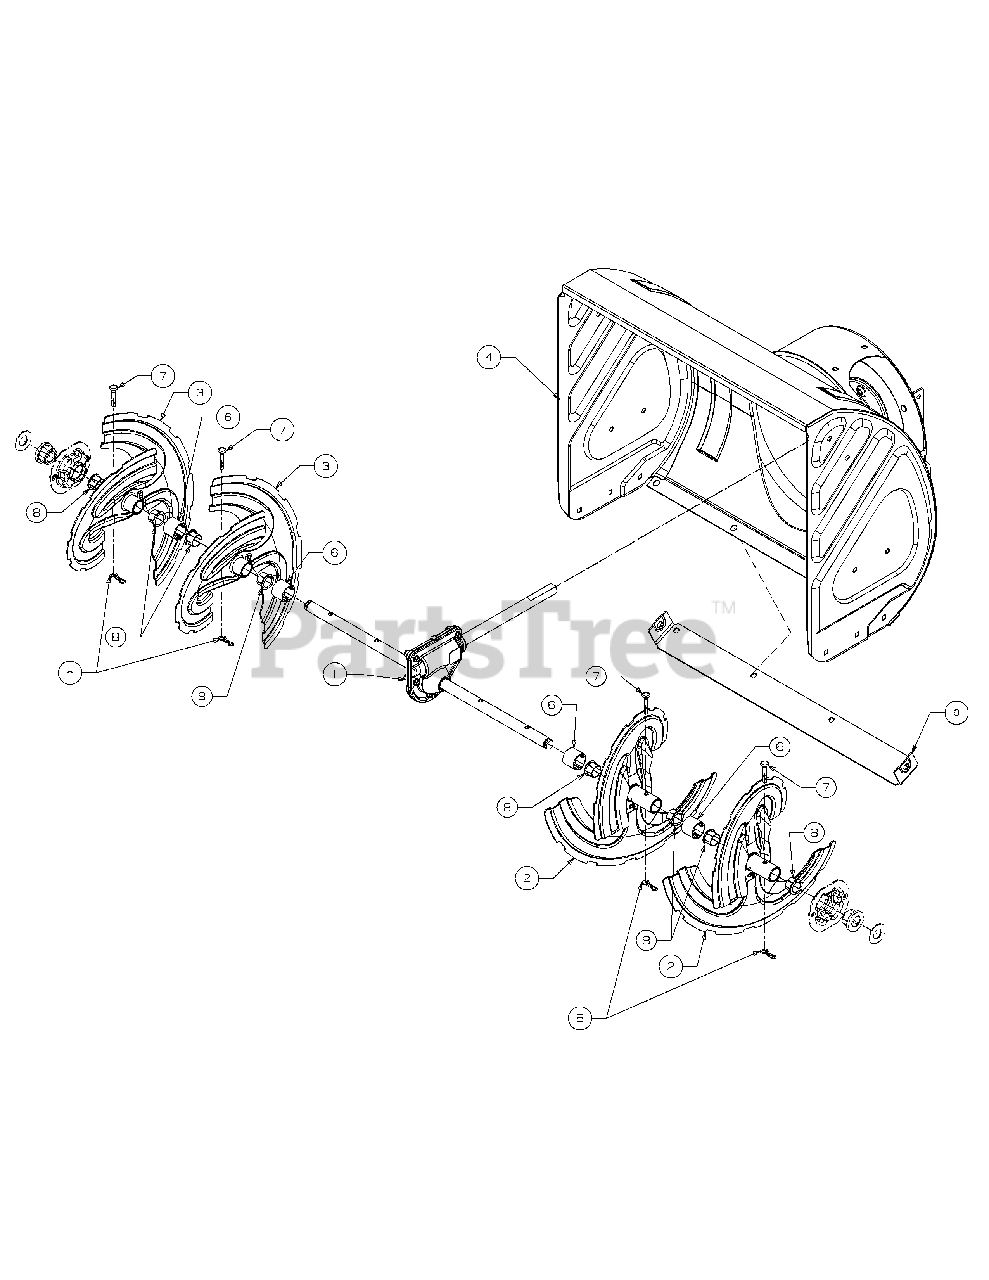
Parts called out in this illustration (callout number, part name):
1	Gearbox Asm-Au
2	Auger Assembly-LH
3	Auger Assembly-RH
4	Housing Assy-Auger
5	Pin-Cotter
6	Spacer 1.25Od X
7	Pin-Shear .25
8	Flange Bearing
9	Plate-Shave 24"
